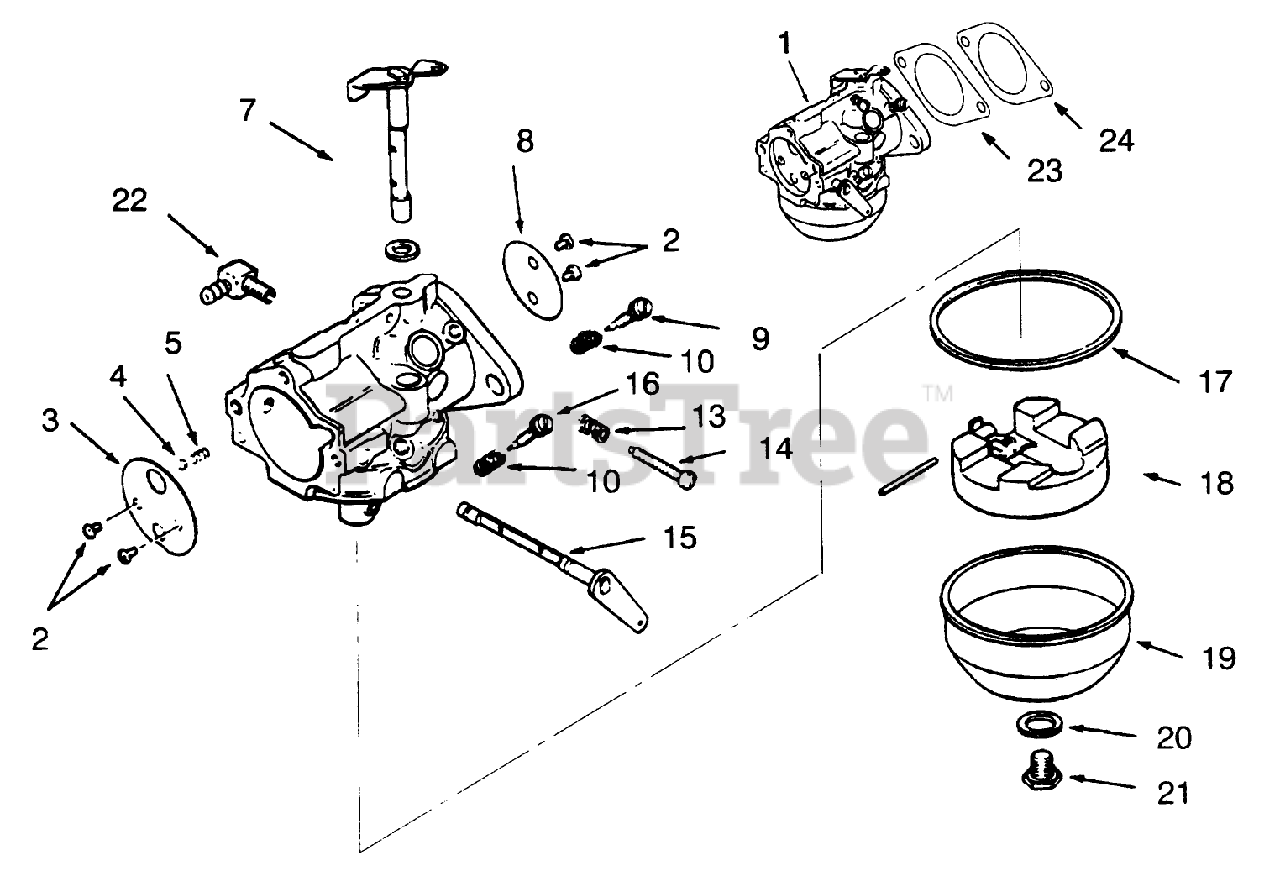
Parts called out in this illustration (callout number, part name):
1	KOHLER 47-853-29
2	KOHLER 25-086-27
3	VNDR #47-146-09
4	KOHLER 25-194-01
5	KOHLER 25-089-03
7	VNDR #14-144-25
8	VNDR #47-146-10
9	KOHLER 25-368-01
10	KOHLER 25-089-02
13	KOHLER 25-089-04
14	KOHLER 25-086-26
15	KOHLER 47-090-38
16	KOHLER 25-368-03
17	KOHLER 25-041-04
18	KOHLER 25-757-09
19	KOHLER 25-104-01
20	KOHLER 25-041-03
21	KOHLER 25-100-05
22	KOHLER 25-155-02
23	KOHLER 47-049-01
24	KOHLER 271030
